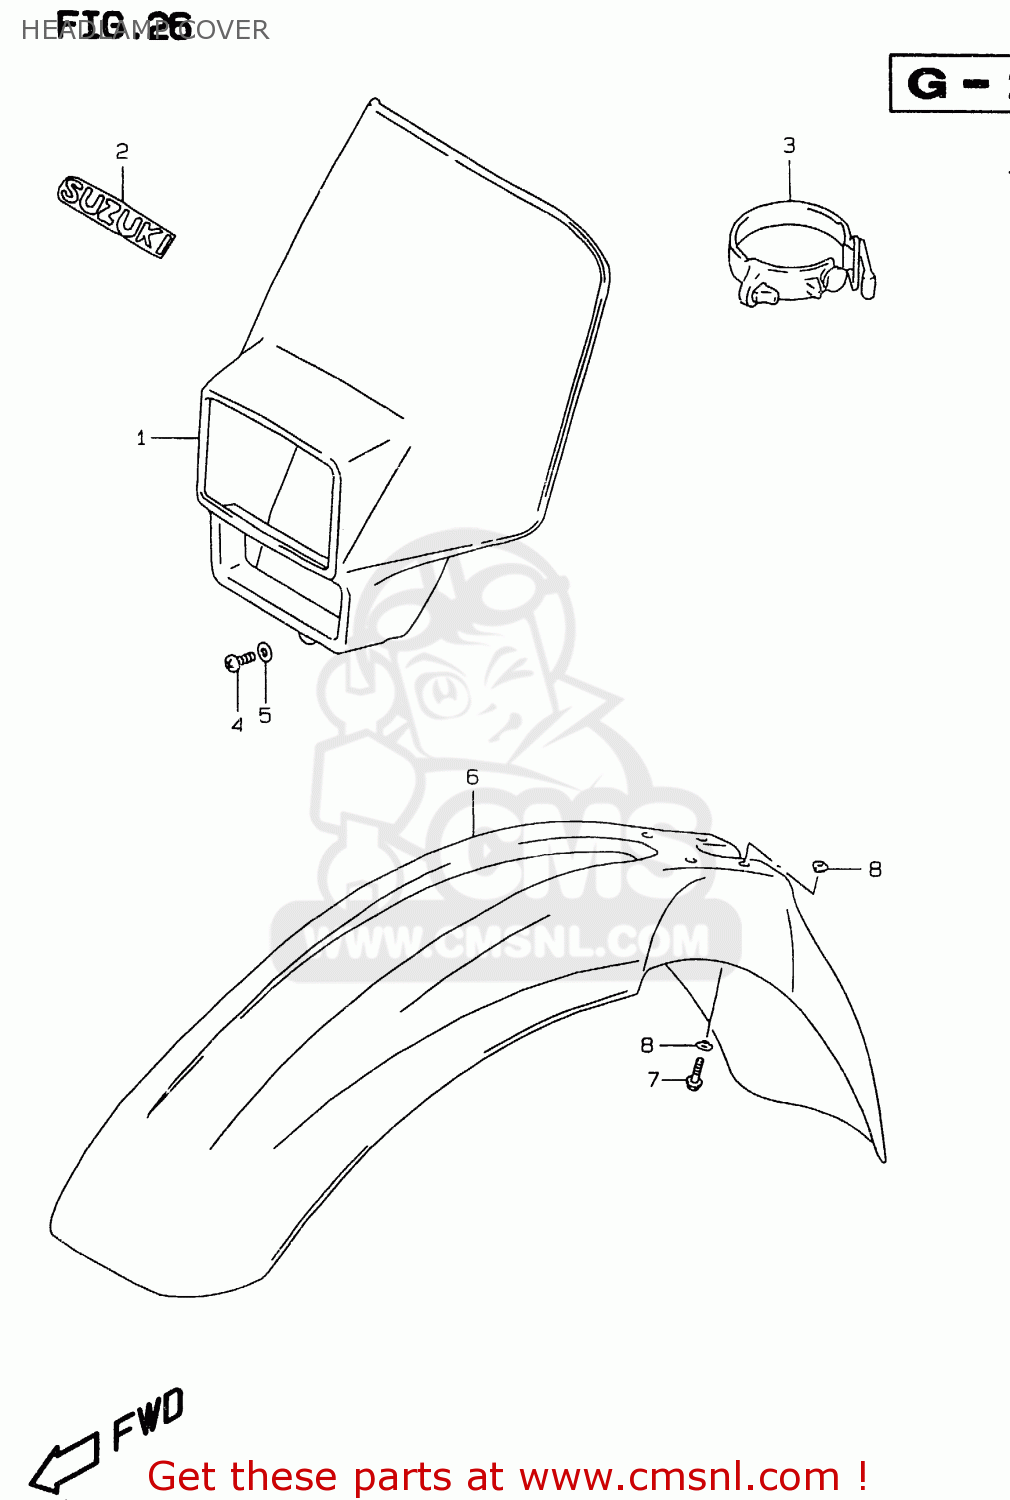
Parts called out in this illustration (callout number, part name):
1	COVER,HEADLAMP
2	EMBLEM,HEADLAMP COVER
3	BAND,HEADLAMP COVER
4	SCREW
5	WASHER
6	FENDER,FRONT (YELLOW)
7	BOLT
8	WASHER
